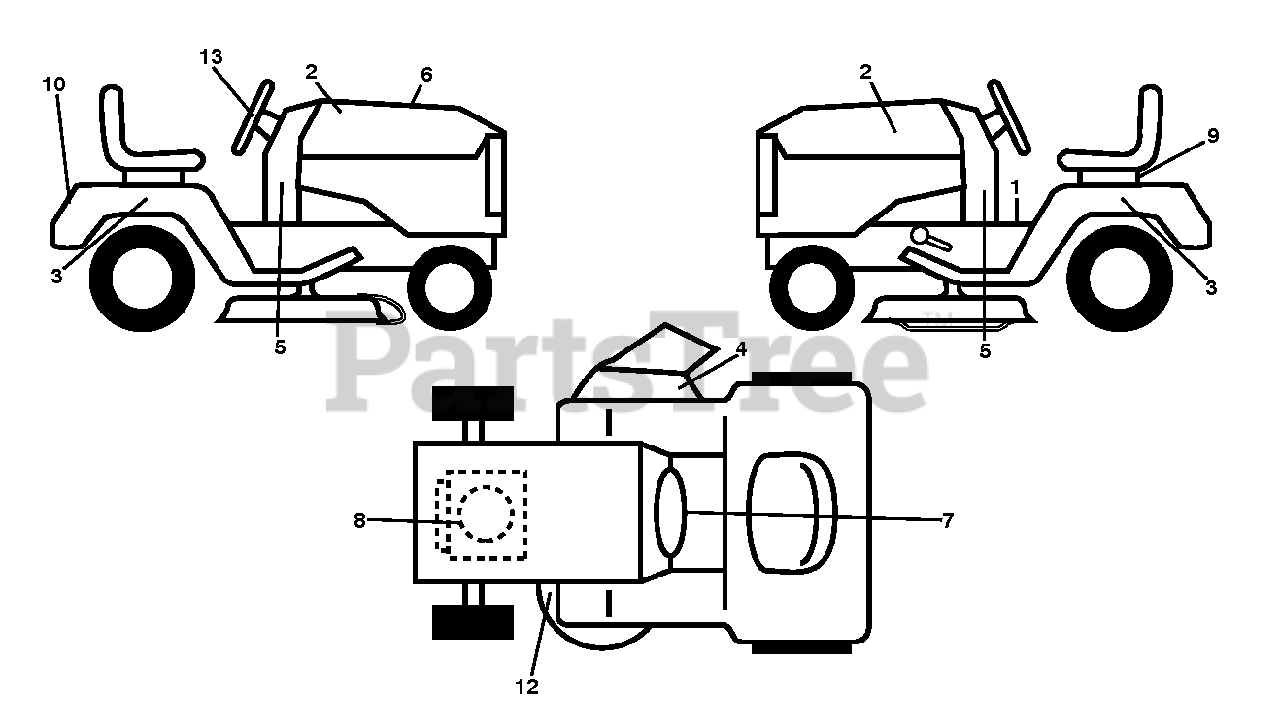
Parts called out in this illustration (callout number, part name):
2	DECAL.HOOD.ALPHA.RH/LHSET.2014
3	DECAL FENDER
4	DECAL.MOWER.WARN.KEEP.HAND.AWY
5	DECAL.DASH.LOWER.145/38.11POU
7	DCL.WARNING.SPARK.IGNITION.CA
8	DECAL.ENG.BS.14_5PB.DOM.381666
9	DECAL BTRY SYMBOLS
10	DECAL.FNDR.LOGO.2014.POULAN
12	DECAL.DECK.SCH.36,38,94.NONCR
